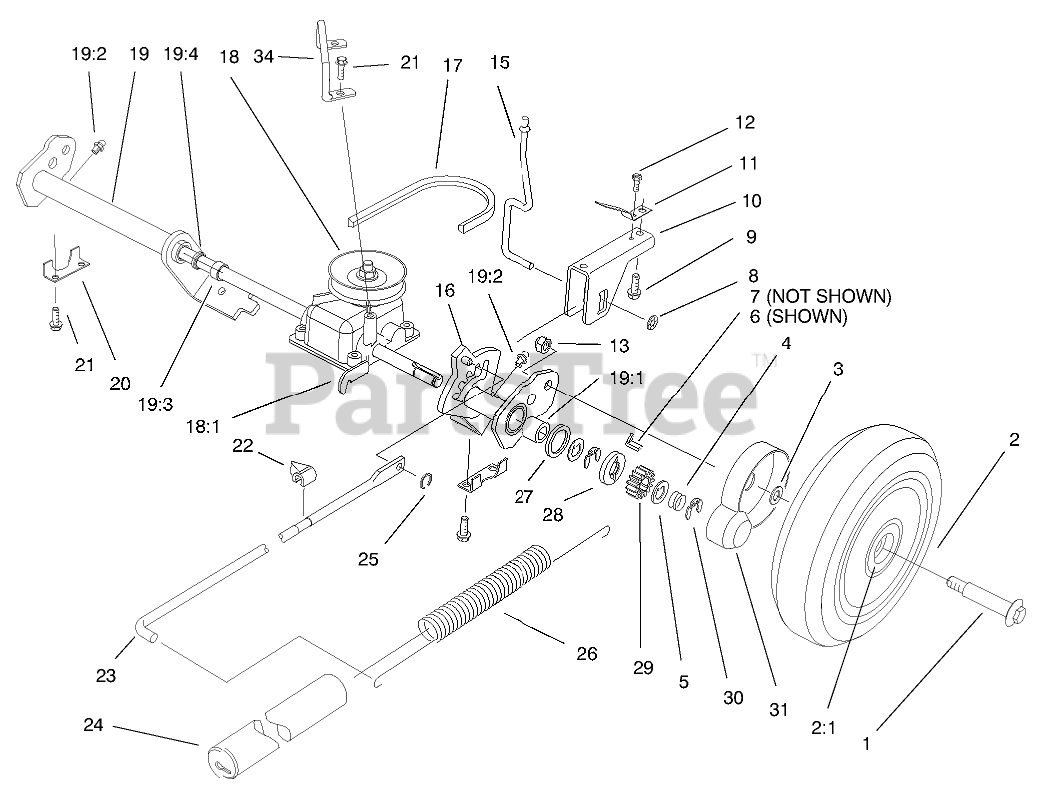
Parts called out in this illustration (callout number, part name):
1	BOLT-SHOULDER
2	WHEEL AND GEAR ASM
2:1	BUSHING
3	SPACER-COVER, WHEEL
4	SPRING-COMPRESSION
5	WASHER-THRUST, KEYED
6	KEY-ROCKING, LH
7	KEY-ROCKING, RH
8	PUSHNUT
9	SCREW
10	SADDLE - HOC
11	SPRING - TRIGGER RET
12	SCREW 8 - 32 X 250
15	TRIGGER ROD
16	ASM - LH PIVOT ARM
17	V-BELT
18	GEAR CASE ASSY
18:1	TRACTION BRACKET
19	ASM - RH PIVOT ARM
19:1	BEARING-ROLLER
19:2	FITTING-GREASE
19:3	BUSHING
19:4	SEAL-OIL
20	REAR SECURING PLATE
21	SCREW-HWH
22	INDICATOR-HEIGHT OF CUT
23	LINK ROD
24	COVER-SPRING
25	GRIP RING
26	SPRING-COUNTERBALANCE
27	RING-FRICTION
28	WASHER-CLUTCH
29	GEAR-PINION
30	RING-CLIP, LOCKING
31	COVER-WHEEL
34	Retainer Belt
